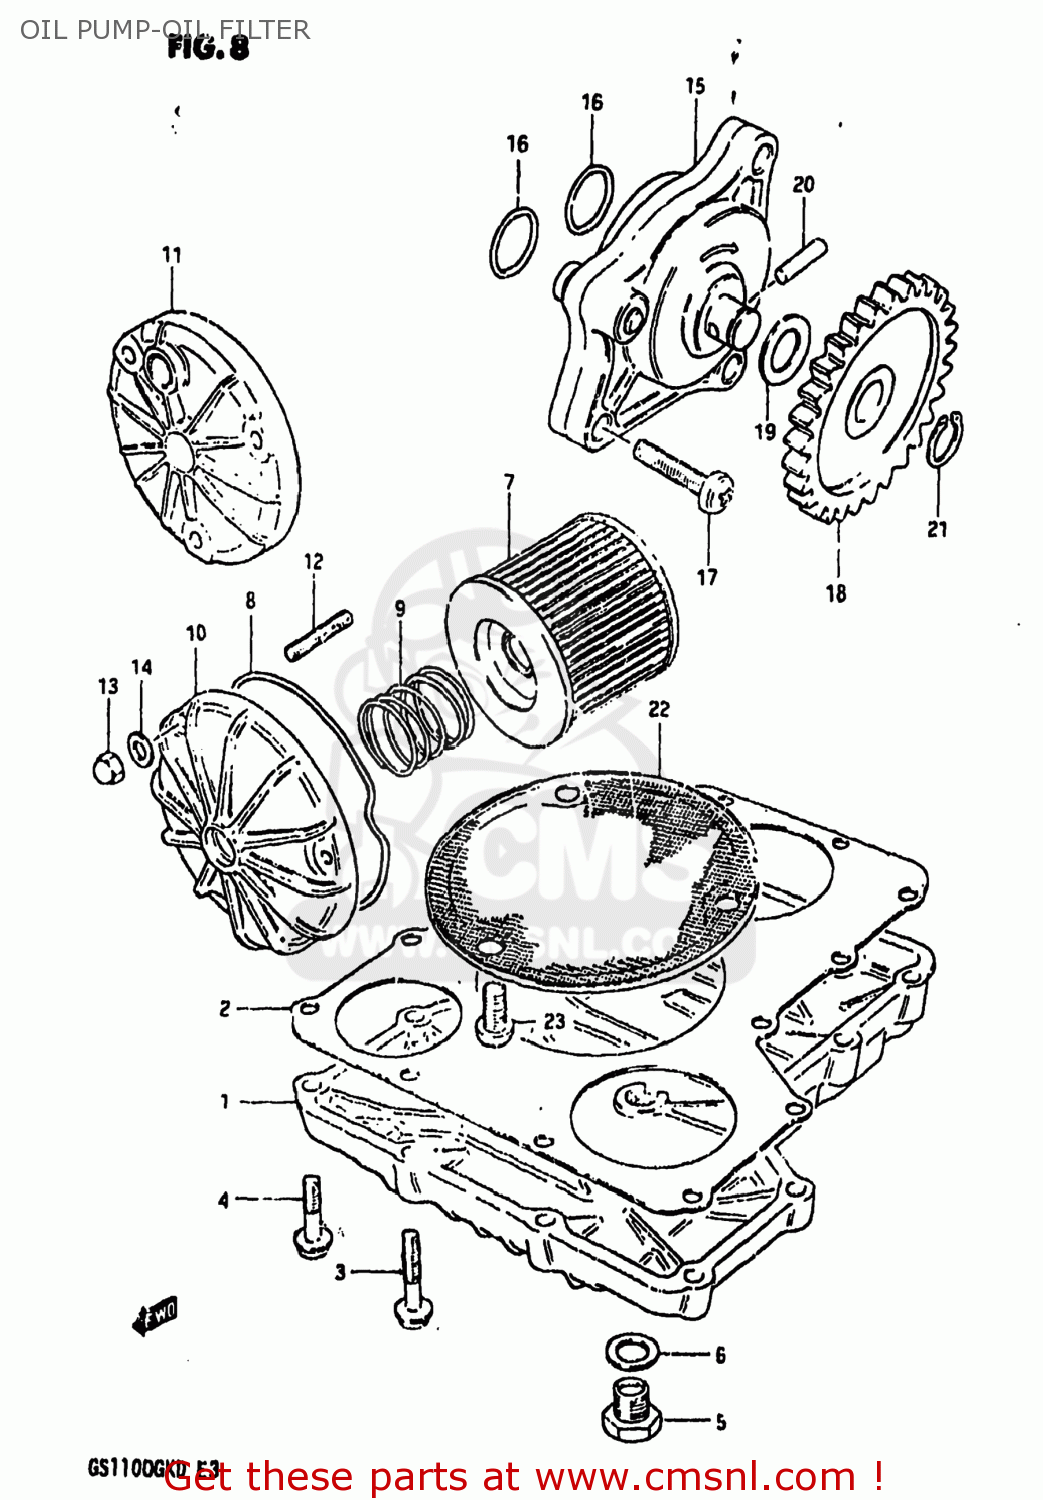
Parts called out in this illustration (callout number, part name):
1	PAN,OIL
2	GASKET,OIL PAN (MCA)
3	BOLT
4	BOLT
5	PLUG
6	GASKET(14X19.2X2) (NAS)
7	FILTER ASSY,ENGINE OIL
8	O RING,OIL FILTER CHAMBER CAP
9	SPRING
10	CAP,ENGINE OIL FILTER
11	CAP,OIL FILTER
12	STUD 6X20
13	NUT
14	WASHER
15	PUMP ASSEMBLY,ENGINE OIL
16	O RING(D:1.9,ID:13)
17	SCREW
18	GEAR,ENG OIL PUMP DRIVEN(NT:33
19	SHIM
20	PIN(4X15.8)
21	CIRCLIP
22	STRAINER,ENGINE OIL
23	SCREW 6X12
